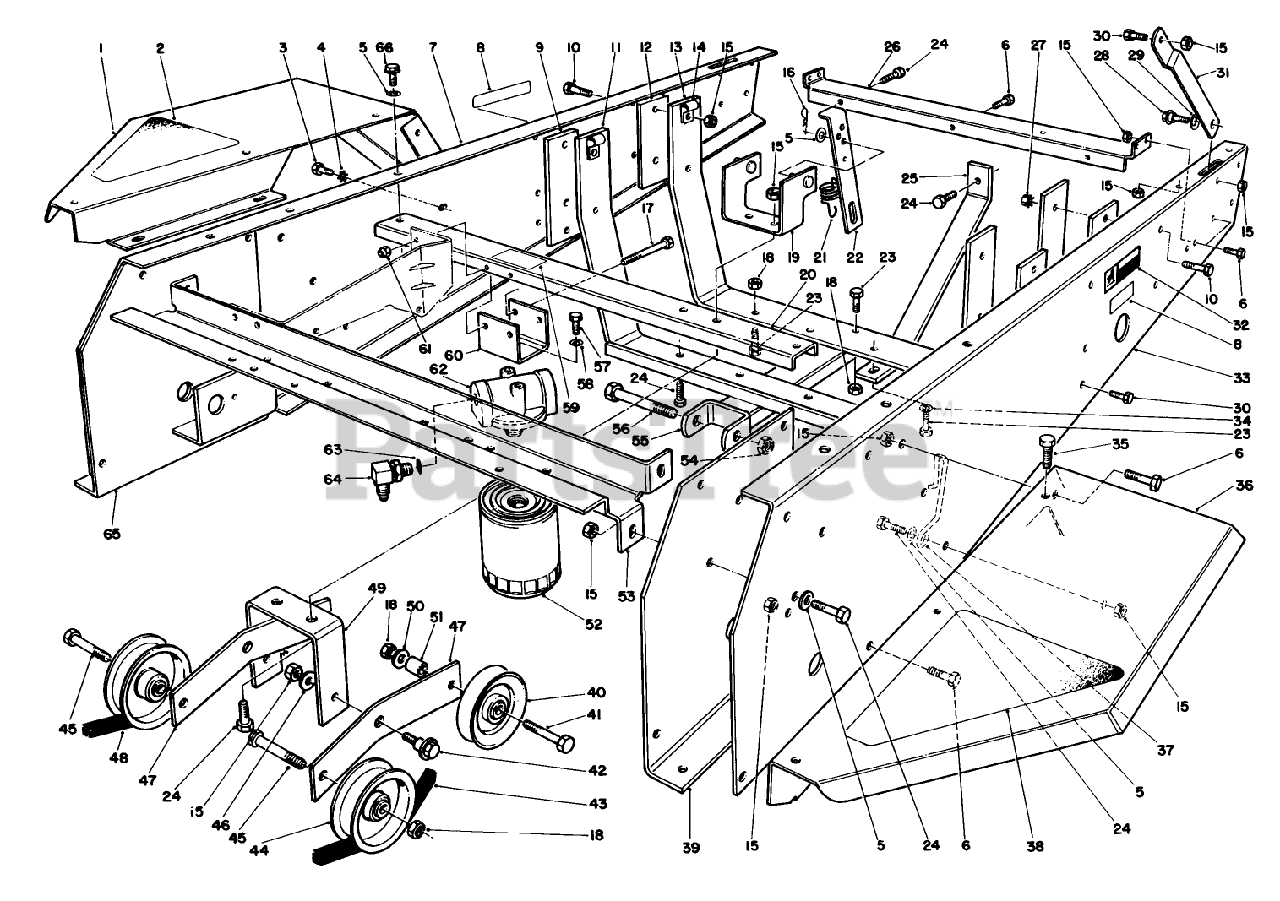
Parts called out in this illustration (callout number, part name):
1	Fender R.H
2	RH FENDER PAD
3	SCREW-HH
4	WASHER-LOCK
5	WASHER-PLAIN
6	SCREW-HH
7	Channel-Side R.H.
8	DECAL-ROTATING
9	FRONT ENG PLATE
10	SCREW-HH
11	ENGINE MT WA B
12	REAR ENG PLATE
13	ENGINE MOUNT B
14	CLAMP-R
15	NUT-LOCK, NI
16	PIN-COTTER
17	SCREW-HH
18	NUT-LOCK, NI
19	Anchor-Spring
20	MIDDLE CHANNEL WA B
21	IDLER SPRING
22	IDLER ANCHOR LINK
23	SCREW-HH
24	SCREW-HH
25	TENSION BAR B
26	Support-Shield
27	NUT-KEPS
28	SCREW-SHOULDER
29	WASHER-SPRING
30	SCREW-HH
31	Stop-Hood Lower
32	DECAL-HOT
33	Channel-Side LH.
34	WASHER-LOCK
35	SCREW-HHFTF
36	Fender L.H.
37	BELT GUIDE
38	LH FENDER PAD
39	Axle Stand-LH.
40	PULLEY
41	SCREW-HH
42	SCREW-SHOULDER
43	V-BELT, JACKSHAFT
44	PULLEY
45	SCREW-HH
46	WASHER
47	IDLER LEVER
48	V-BELT, TRACTION
49	IDLER MT BRKT
50	WASHER-FLAT
51	SPACER-WEIGHT
52	FILTER-OIL, TRANSMISSION
53	Channel-Front
54	NUT-LOCK
55	CYL MOUNT WA B
56	SCREW-HH
57	SCREW-HH
58	WASHER-LOCK
59	DECAL-OIL
60	BRACKET - FILTER HEAD
61	NUT-LOCK, NI
62	FILTER HD ASM
63	O-RING
64	FITTING-ELBOW, 90
65	Axle Stand R.H.
66	SCREW-HWHTF
